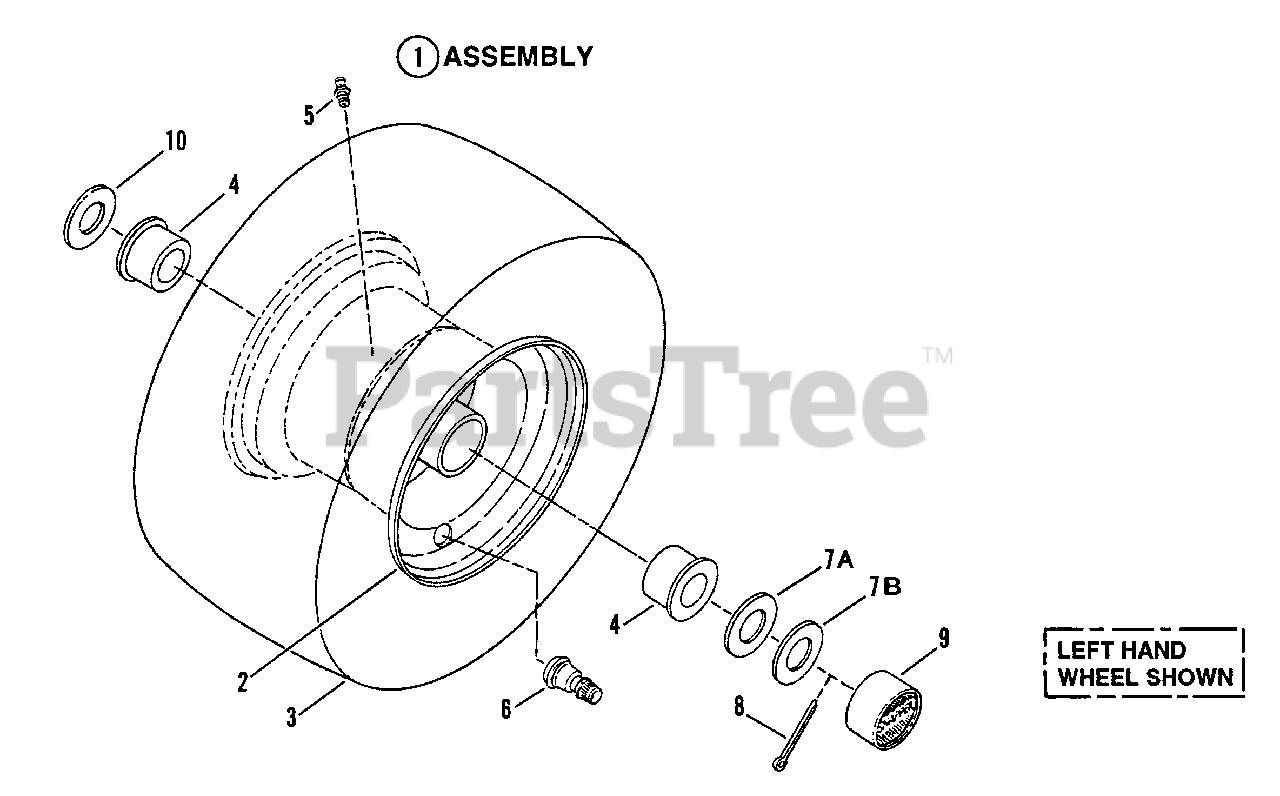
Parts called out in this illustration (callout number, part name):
1	ASSEMBLY, Front Tire & Rim
2	RIM, 5.50 x 4.00
3	TIRE, 13 x 5.00
3	TIRE, 15 x 6.00
4	BEARING, Wheel
5	FITTING, Lube 1/4-28 Tapered Thread
6	VALVE, Air (Snap-in)
7A	WASHER, 3/4 I.D. x 1 1/2 O.D. Flat
7B	WASHER, 3/4 I.D. x1 5/8" O.D.Thrust
8	COTTER-PIN
9	HUB-CAP
10	WASHER, 25/32 I.D. x 1 1/2" O.D.
